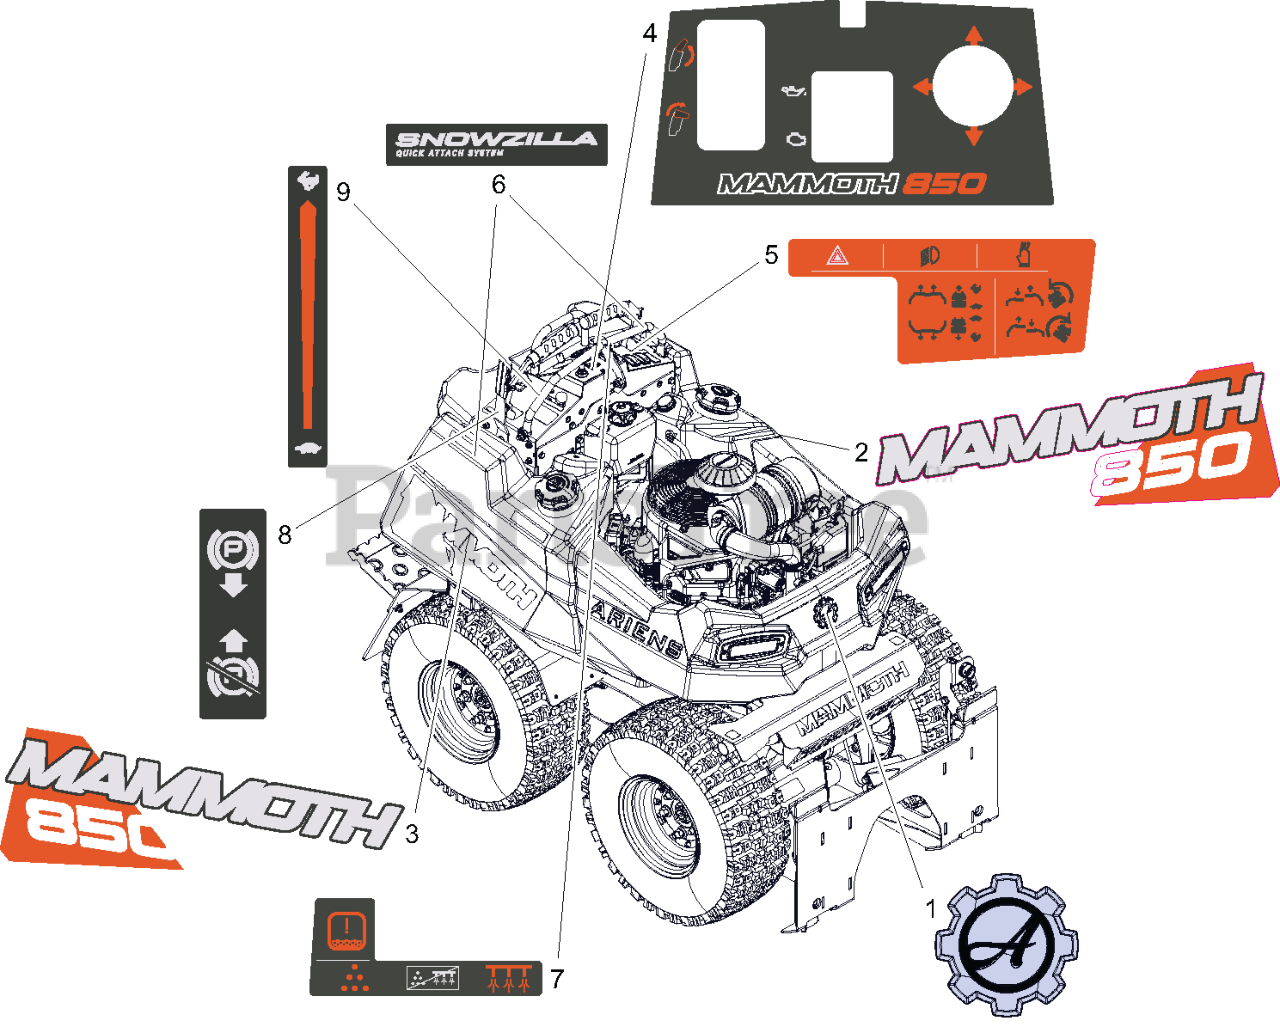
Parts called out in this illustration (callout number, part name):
1	DECAL, ARIENS - GEAR BADGE
2	DECAL- MAMMOTH 850 - LH
3	DECAL- MAMMOTH 850 - RH
4	DECAL, DASH - MAMMOTH
5	DECAL, DASH - CONTROLS
6	DECAL, SNOWZILLA - QUICK ATCH
7	DECAL, CONTROL - BRINE SPRAY
8	DECAL, CONTROL - BRAKE
9	DECAL, CONTROL - SPEED
